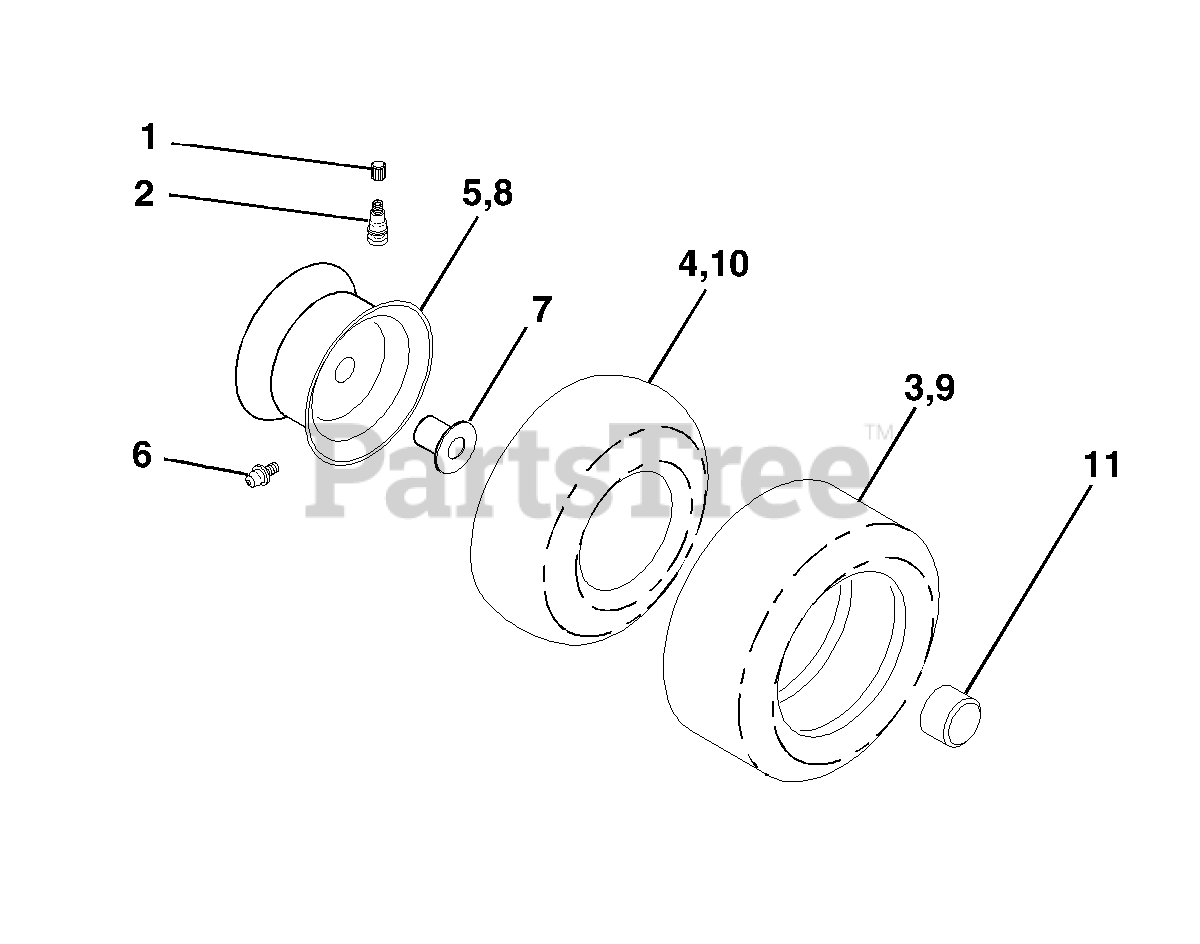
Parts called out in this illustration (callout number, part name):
1	Cap Valve Tire
2	Stem Valve
3	Tire F Ts 15 X 6 0 - 6 Service
4	Tube Front
5	Rim Asm 6"front White Service
6	Fitting Grease
7	Bearing Flange
8	Rim Asm 8"rear White Service
9	Tire R Ts 18x9.5-8 C Service
10	Tube Rear
11	Cap Axle Blk 1 50 X 1 00
